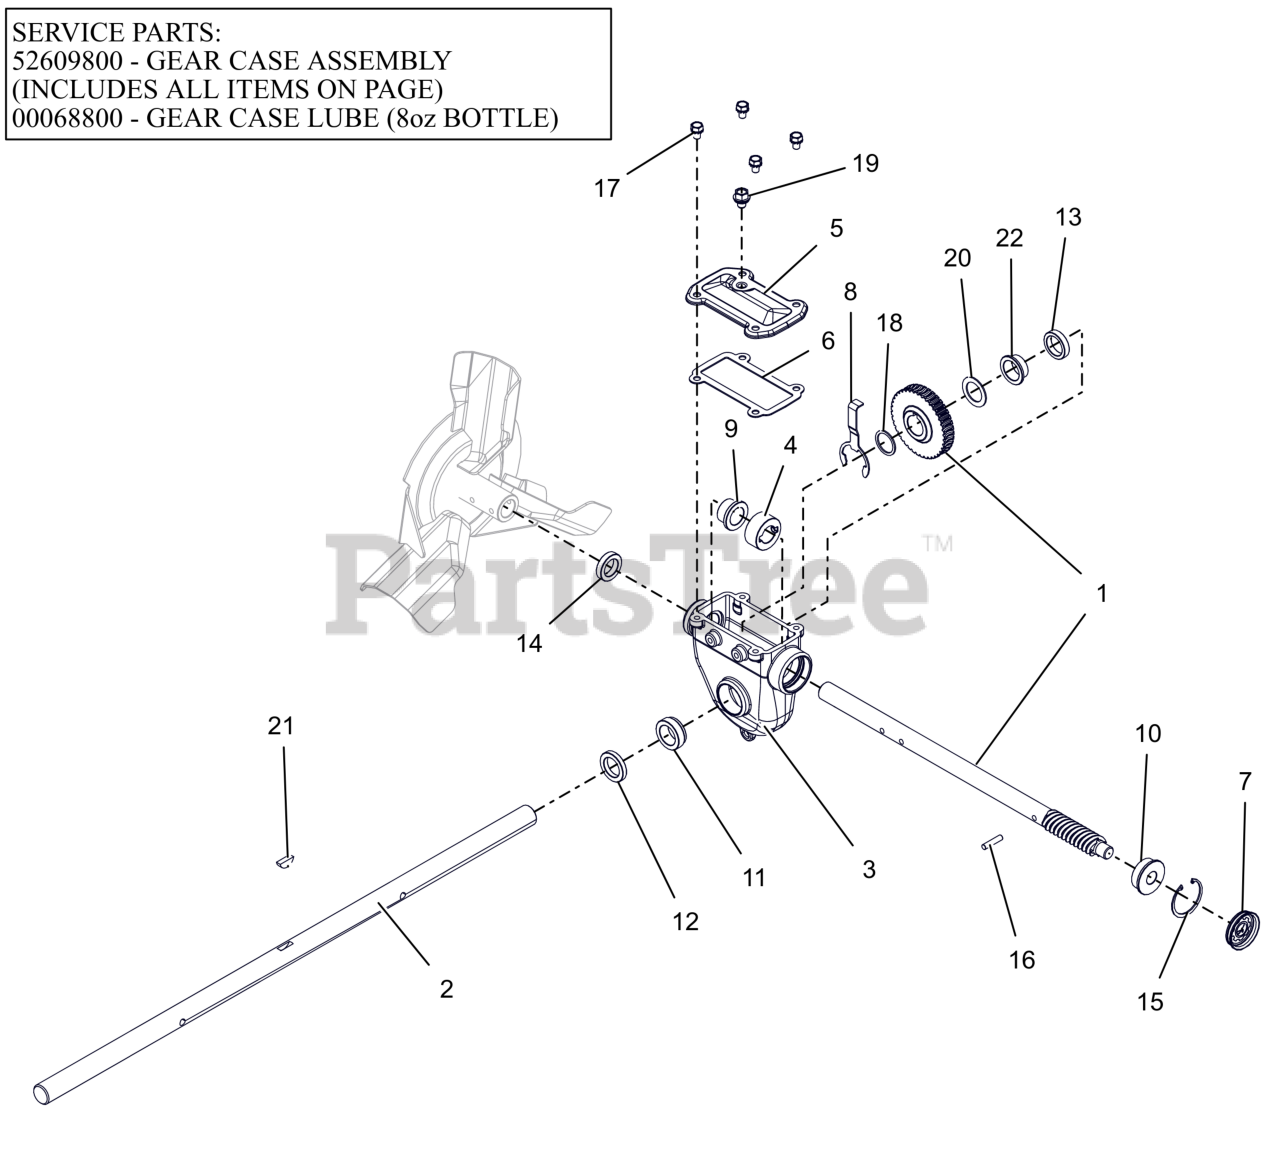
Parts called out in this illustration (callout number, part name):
1	ASSY, WORM SHAFT & GEAR
2	SHAFT, RAKE-32"
3	GEARCASE, LARGE MACHINED
3	GEAR CASE, 32" IRON PRO TOP-LD
3	ARIENS L3 LUBE, 8 OZ BOTTLE
4	THRUST COLLAR, .875"ID SLIPFIT
5	COVER, TOP - LARGE IRON
6	GASKET, TOP - LARGE GEARCASE
7	COVER, GEAR CASE 1.75"
8	BUSHING RETAINER, LARGE
9	BSHG-FLG .879X1.128X.75X1.45
10	BSHG-FLG .628X1.503X.58X1.725
11	BSHG-FLG LARGE, RIGHT
12	SEAL-OIL .999X1.500X.250 TBC29
13	SEAL-OIL .999X1.375X.312 TBC29
14	SEAL-OIL .873X1.375X.312 TBC29
15	RG-RTNG-INT 1.750X.062
16	PIN-STR .250X1.12 6150
17	BLT, SEMS .31-18X.50 G5 ZCC
18	WSHR, FLT 1.010X1.250X.068 ZCC
19	SCR, .380-15X.500 W/SEAL WASHER
20	WSHR, FLT 1.010X1.505X.062 ZCC
21	KEY-WDRF .25X.875 HRD #A
22	BSHG-FLG 1.006X1.128X.555X1.45
